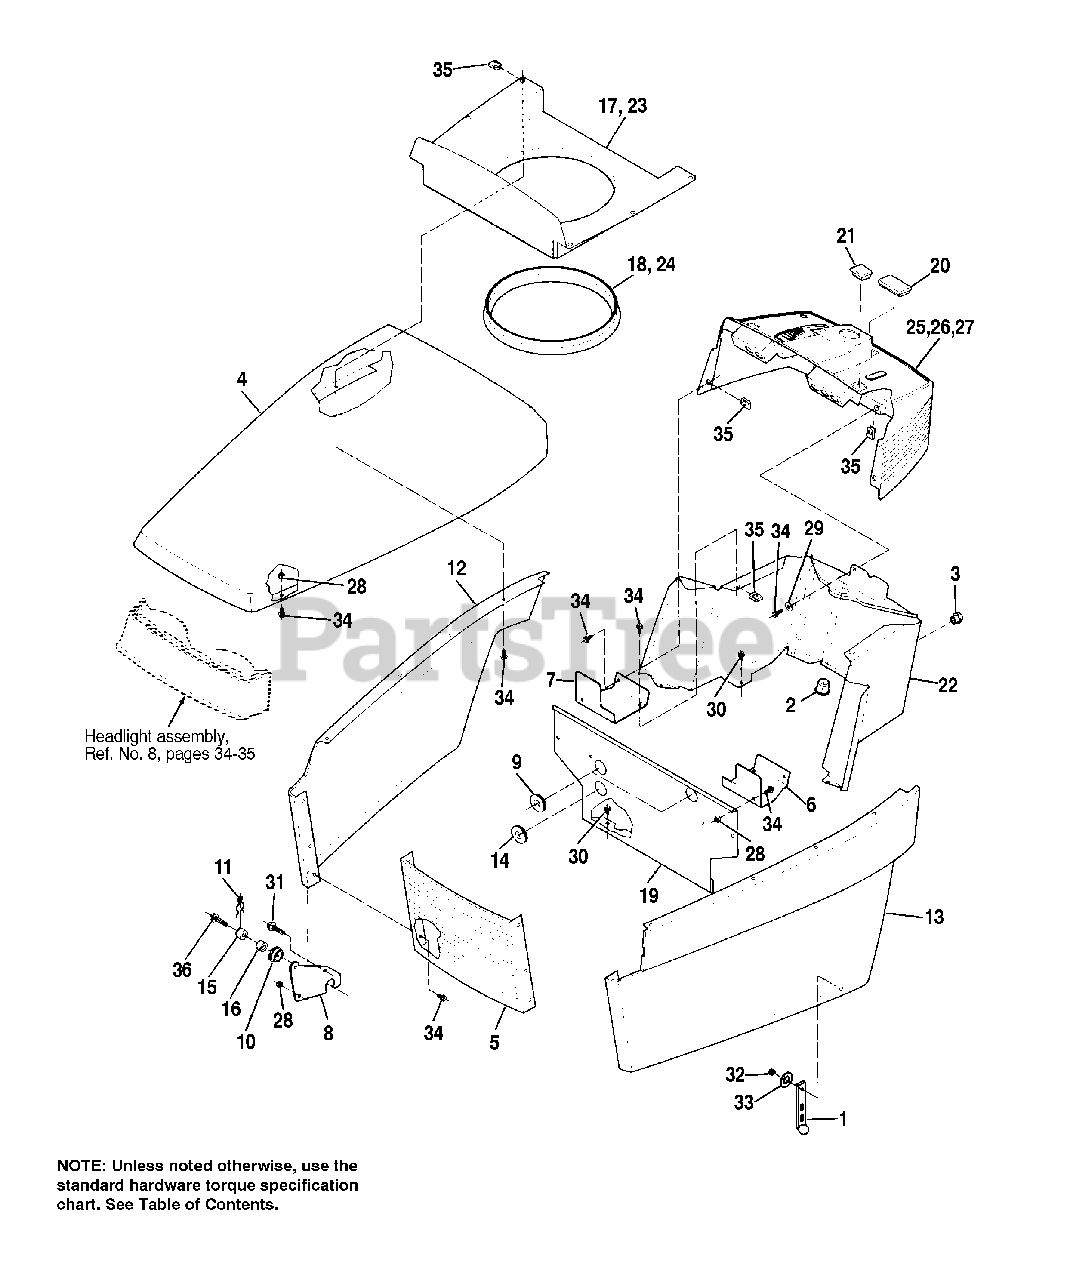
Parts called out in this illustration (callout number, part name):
1	STRAP, Hood
2	BUSHING, Nylon
3	PLUG, Bumper
4	HOOD, Orange
4	HOOD, Red
5	GRILLE
6	SUPPORT, Bulkhead, LH
7	SUPPORT, Bulkhead, RH
8	HINGE, Hood
9	GROMMET, Bulkhead
10	SPACER, Hood
11	CLIP, Hairpin
12	SIDE PANEL ASSY., RH, Orange
12	SIDE PANEL ASSY., RH, Red
13	SIDE PANEL ASSY., LH, Orange
13	SIDE PANEL ASSY., LH, Red
14	GROMMET, Wire Harness
15	PIVOT, Hood
17	AIR DUCT
18	MOLDING, Air Duct
19	BULKHEAD
20	PLUG, Hole, Hourmeter
21	PLUG, Hole, Electric Lift
22	DASH, Lower
23	AIR DUCT
24	MOLDING, Air Duct
25	DASH ASSY.
26	DASH ASSY.
27	DASH ASSY.
28	NUT, Hex, Nylon, Lock, 1/4-20
29	WASHER, Plain, 1/4
30	SCREW, Taptite, 1/4-20 x 1/2
31	SCREW, Taptite, 5/16-18 x 5/8
32	NUT, Hex, Nylon, Lock, #10-24
33	WASHER
34	CAPSCREW, Whizlock, 1/4-20 x 5/8
35	PAL NUT, 1/4-20
36	SCREW, Taptite, 5/16-18 x 1
